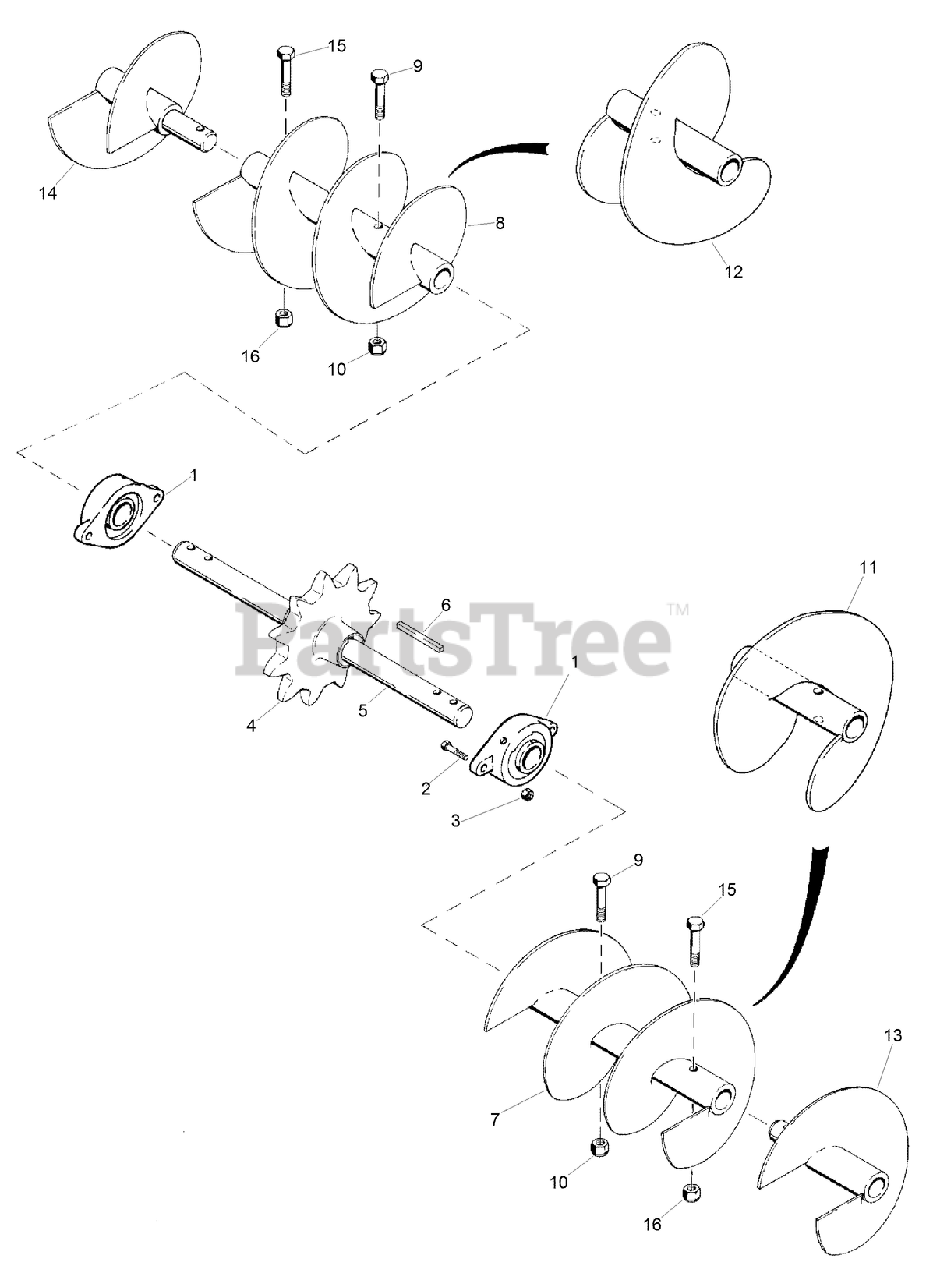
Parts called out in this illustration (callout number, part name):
1	BEARING-BALL, 2-BOLT FLANGE (2 IN)
2	BOLT - 5/8 x 2-1/2
3	NUT-LOCK, HEX
4	SPROCKET - Auger Drive, 311 Chain
4	SPROCKET - Auger Drive, 408 Chain
5	SHAFT-AUGER
6	KEY-SQUARE
7	AUGER - RH
8	AUGER - LH
10	NUT-Prev Trq 3/4 GRC CAD Direct
11	WELDMENT - Auger, RH
12	WELDMENT - Auger, LH
13	AUGER - RH, Extension
14	AUGER - LH, Extension
15	BOLT - 9/16 x 3
16	NUT-HEX
